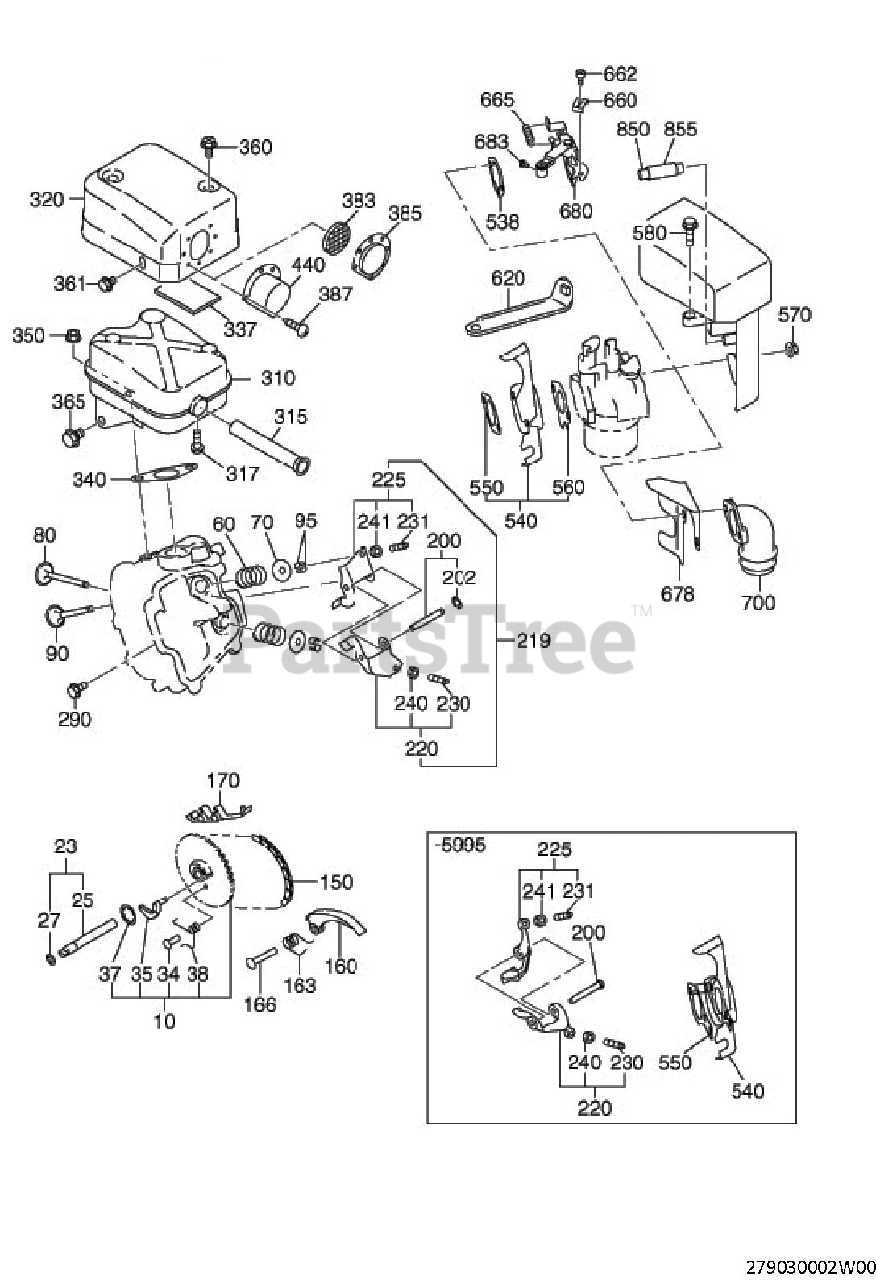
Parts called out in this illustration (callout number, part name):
10	CAM SHAFT CP
25	PIN(CAM SHAFT)
27	O RING
34	PIN(SPRING)
37	CLIP
38	RETURN SPRING
60	VALVE SPRING
70	SPRING RETAINER
80	INTAKE VALVE
90	EXHAUST VALVE
150	TIMING CHAIN CP
163	SPRING(TENTIONER)
166	PIN(TENTIONER)
200	PIN(ROCKER) CP
220	ROCKER ARM(IN) AY
225	ROCKER ARM(EX) AY
230	ADJUST SCREW
231	ADJUST SCREW
240	NUT
241	NUT
290	FLANGE BOLT
315	SPARK ARRESTER CP
317	TAPPING SCREW
320	MUFFLER COVER CP
340	GASKET(MUFFLER)
360	TAPPING BOLT
361	FLANGE BOLT
365	FLANGE BOLT
387	TAPPING SCREW
440	DEFLECTOR CP
540	INSULATOR CP
550	GASKET2(INSULATOR)
560	GASKET1(INSULATOR)
570	FLANGE NUT
580	FLANGE BOLT
